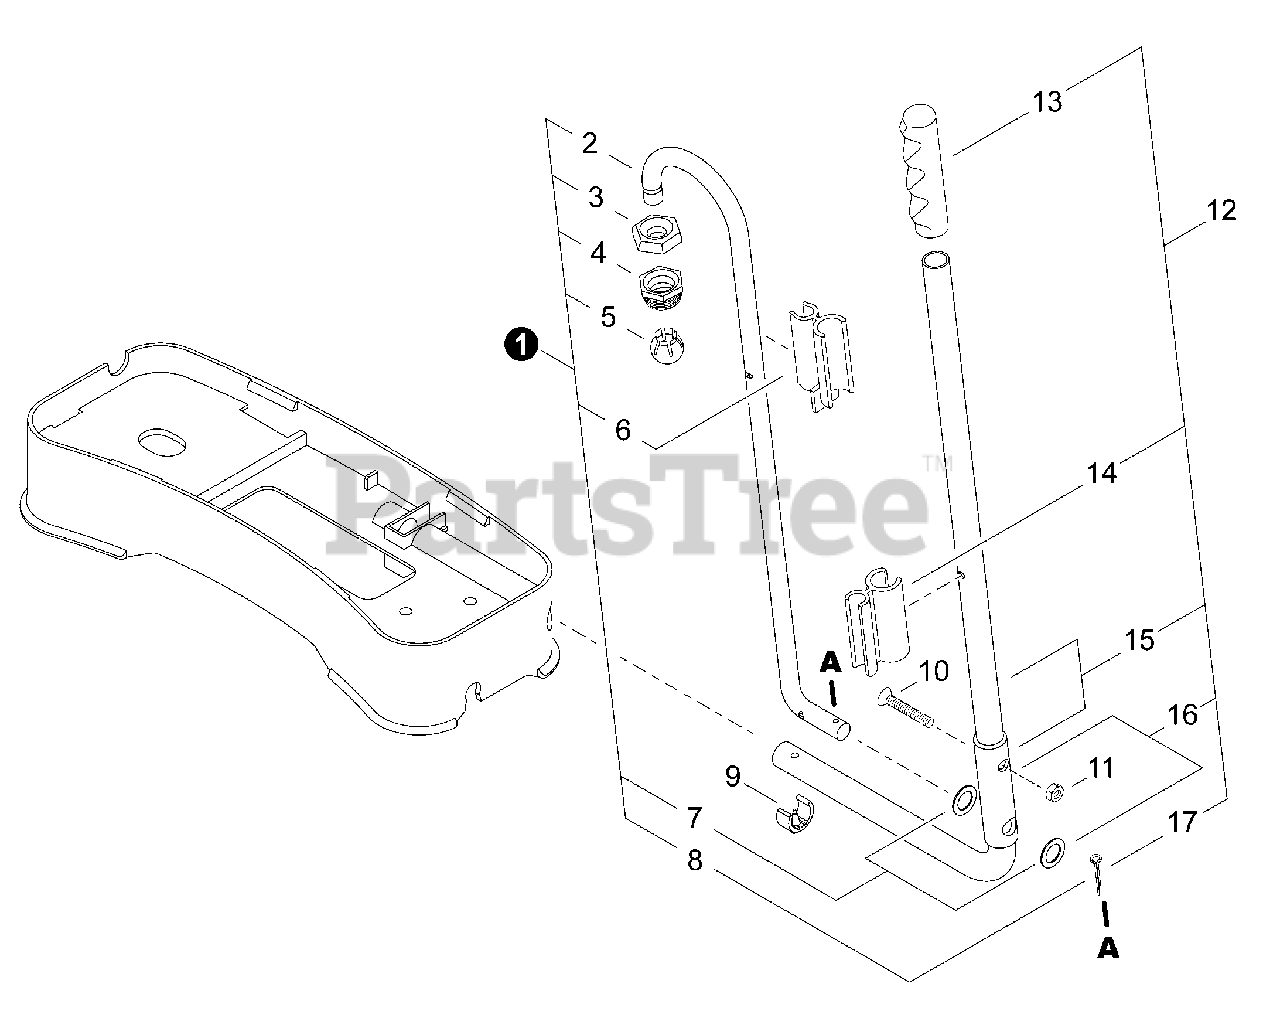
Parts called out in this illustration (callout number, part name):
1	PUMP ARM KIT
2	ARM, PUMP
3	BOOT, JOINT
4	NUT, JOINT
5	JOINT, BALL
6	CLIP, PUMP LEVER
7	WASHER
8	PIN, COTTER
9	C-CLIP
11	NUT, LOCK
12	LEVER KIT, PUMP
13	GRIP, LEVER
14	CLIP, WAND
15	LEVER, PUMP
16	WASHER
17	PIN, COTTER
